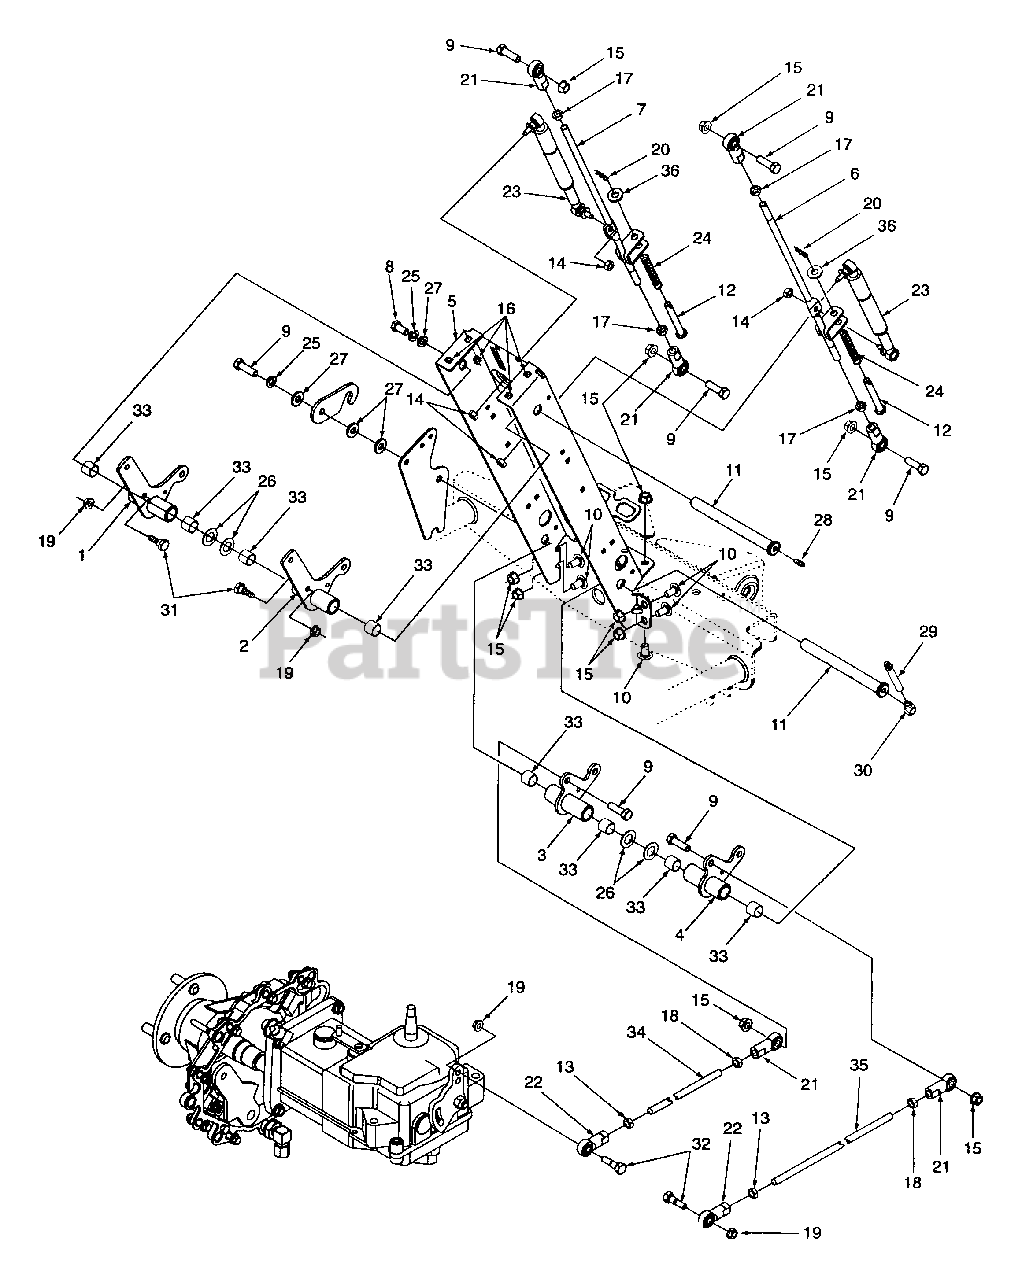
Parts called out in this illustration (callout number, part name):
6	Rod Ass'y, Control RH
7	Rod Ass'y, Control LH
8	Screw, Hex Cap 3/8-16 x 3/4 GR5
9	Screw, Hex Cap 3/8-16 x 1.25 GR5
10	Bolt, Carriage, 3/8-16 x .75
11	Shaft, Control
12	Pin, .374 Dia. x 2.88 Lg
13	Nut, Hex Jam LH Thrd, 3/8-24
14	Nut, Hex Center Lock, M8 GR 8.8
15	Nut, Hex Flange Lock, 3/8-16
16	Nut, Retainer, 1/4-20
17	Nut, Hex Jam, 3/8-24
18	Nut, Hex Jam, 3/8-24
19	Nut, Hex Flange Lock, 5/16-18 GR5
20	Pin, Internal Cotter
21	Rod End, Spherical RH, 3/8-24
22	Rod End, Spherical LH, 3/8-24
23	Cylinder, Damper
24	Spring, Compression
25	Washer, Lock, 3/8
26	Washer, Thrust, .625 x 1.12 x .06
27	Washer, Flat, .406 x .875 x .105
28	Fitting, Grease ,
29	Fitting, Grease w/Tube
30	Adapter, 90° 1/4-20 Thrd
31	Bolt, Shoulder, .437 Dia. x .268
32	Bolt, Shoulder
33	Bearing, Sleeve, .628 x .75 x .625
34	Rod, Control, LH 31-5/8 Lg
35	Rod, Control, RH 35-3/8 Lg
36	Washer, Flat, .406 x .875 x .105
